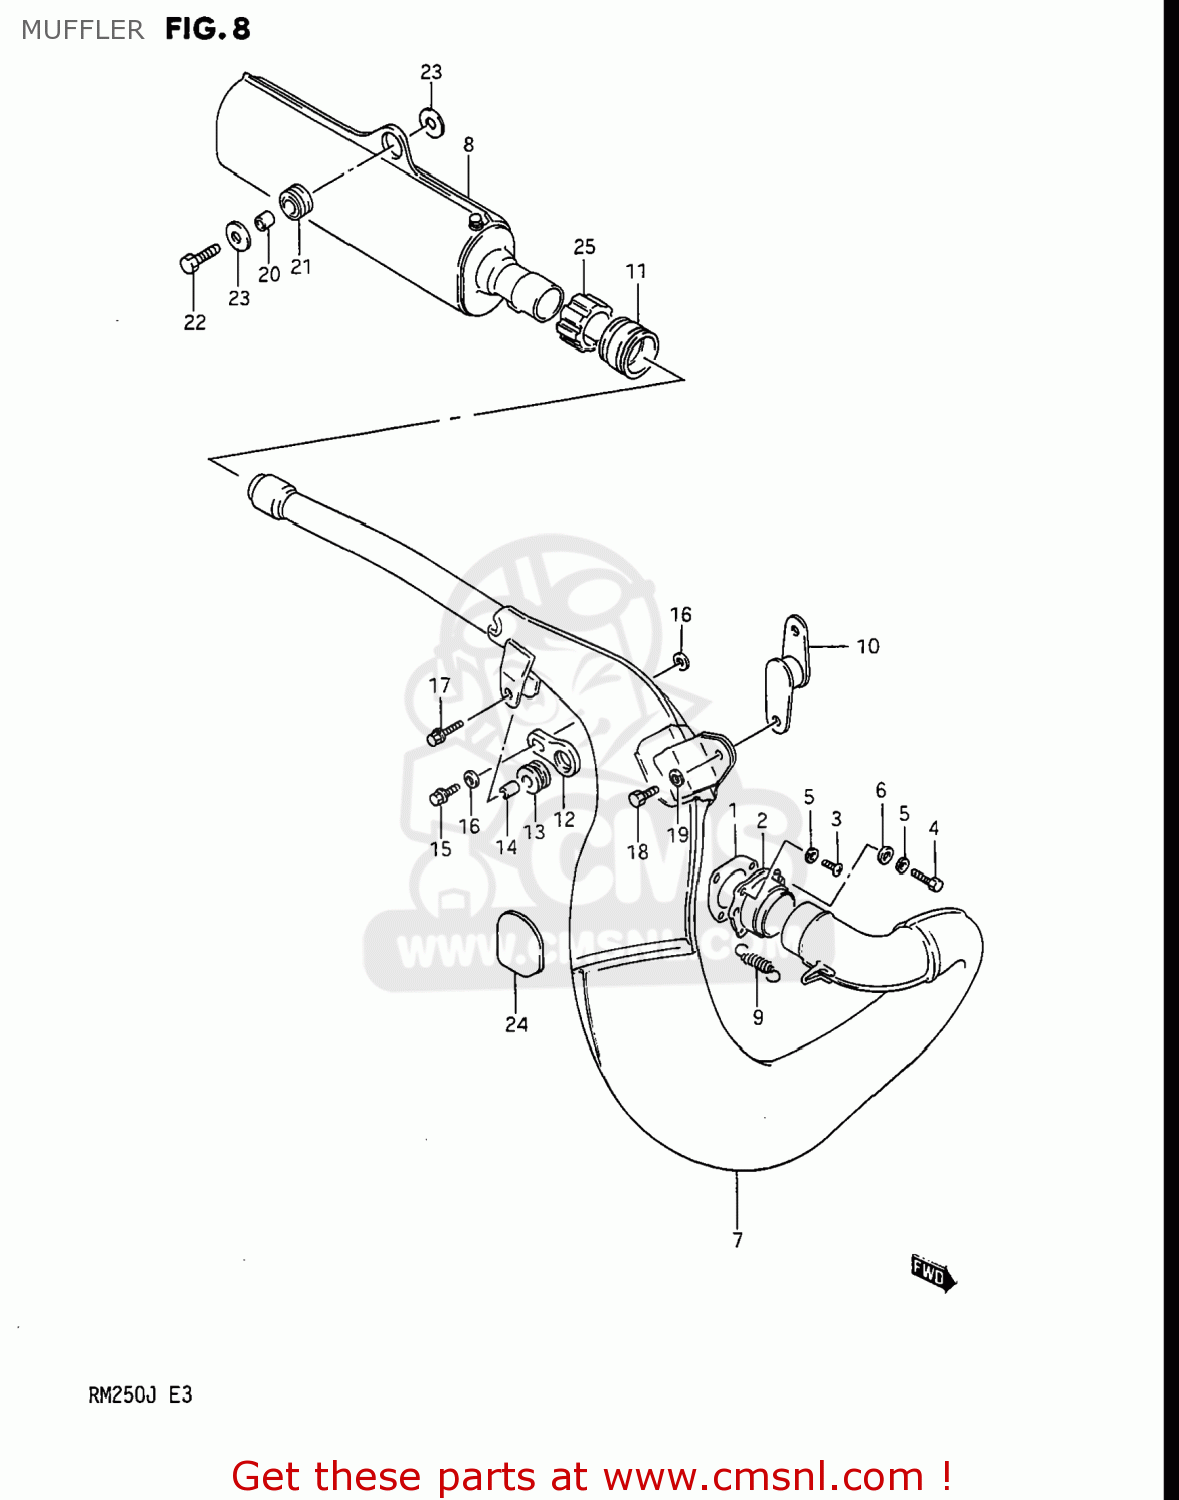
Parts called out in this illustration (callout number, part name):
1	GASKET,EXHAUST PIPE (MCA)
2	FLANGE,EXHAUST PIPE
3	SCREW
4	BOLT(6X20)
5	WASHER,LOCK
6	WASHER(6X10X2)
7	BODY,MUFFLER
8	BODY,MUFFLER,SECOND
9	SPRING
10	DAMPER,MUFFLER SUPPORT
11	CONNECTOR,MUFFLER
12	PLATE,MUFFLER MTG
13	CUSHION,MUFFLER
14	SPACER (6.4X9X13.5)
15	BOLT
16	WASHER (6.5X20X1.2)
17	BOLT
18	BOLT,8X16
19	LOCK WASHER
20	SPACER (8.8X12X11)
21	CUSHION
22	BOLT
23	WASHER (8.1X33X1.6)
24	CUSHION,SPACER
25	CUSHION
